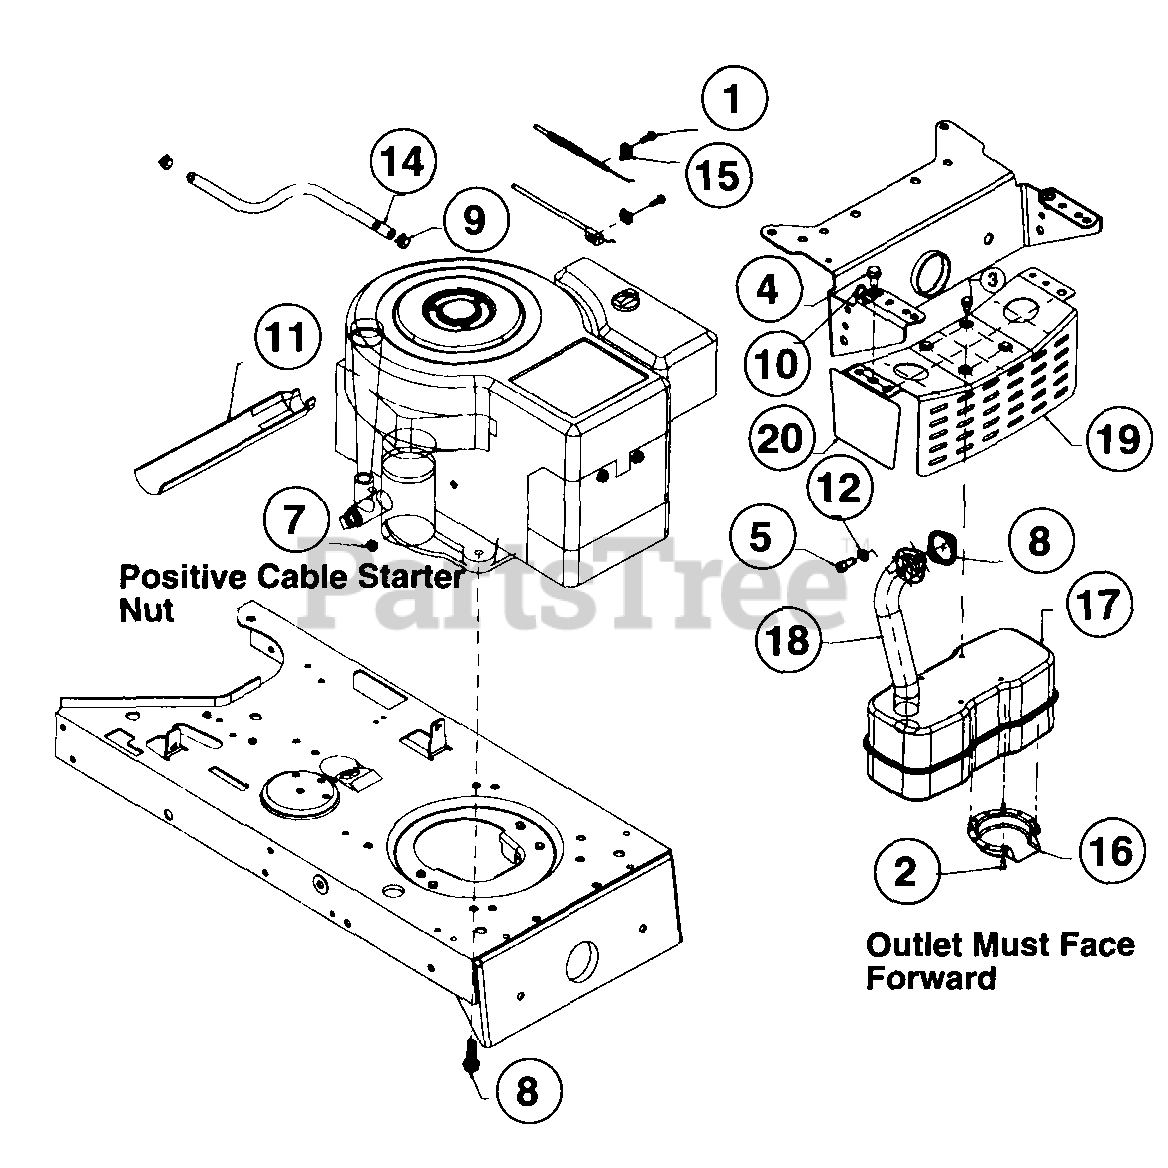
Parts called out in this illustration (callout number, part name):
1	Hex Wash. Scr. #10-32 x .62"
2	Hex Tap Scr. 08-32 x .38" Lg
4	Hex TT-Tap Scr. 5/16-18 x .62"
5	Socket Head Scr. 5/16-18 x .62"
7	Hex Sems Scr. 1/4-20 Thd.
8	Gasket
9	Hose Clamp
10	Clamp
11	Oil Drain Sleeve
12	Lock Washer 5/16" I.D.
14	Fuel Line 12" Lg.
15	Casing Clamp
16	Muffler Deflector
17	Muffler
18	Exhaust Pipe
19	Muffler Brkt
20	Shield Brkt.
